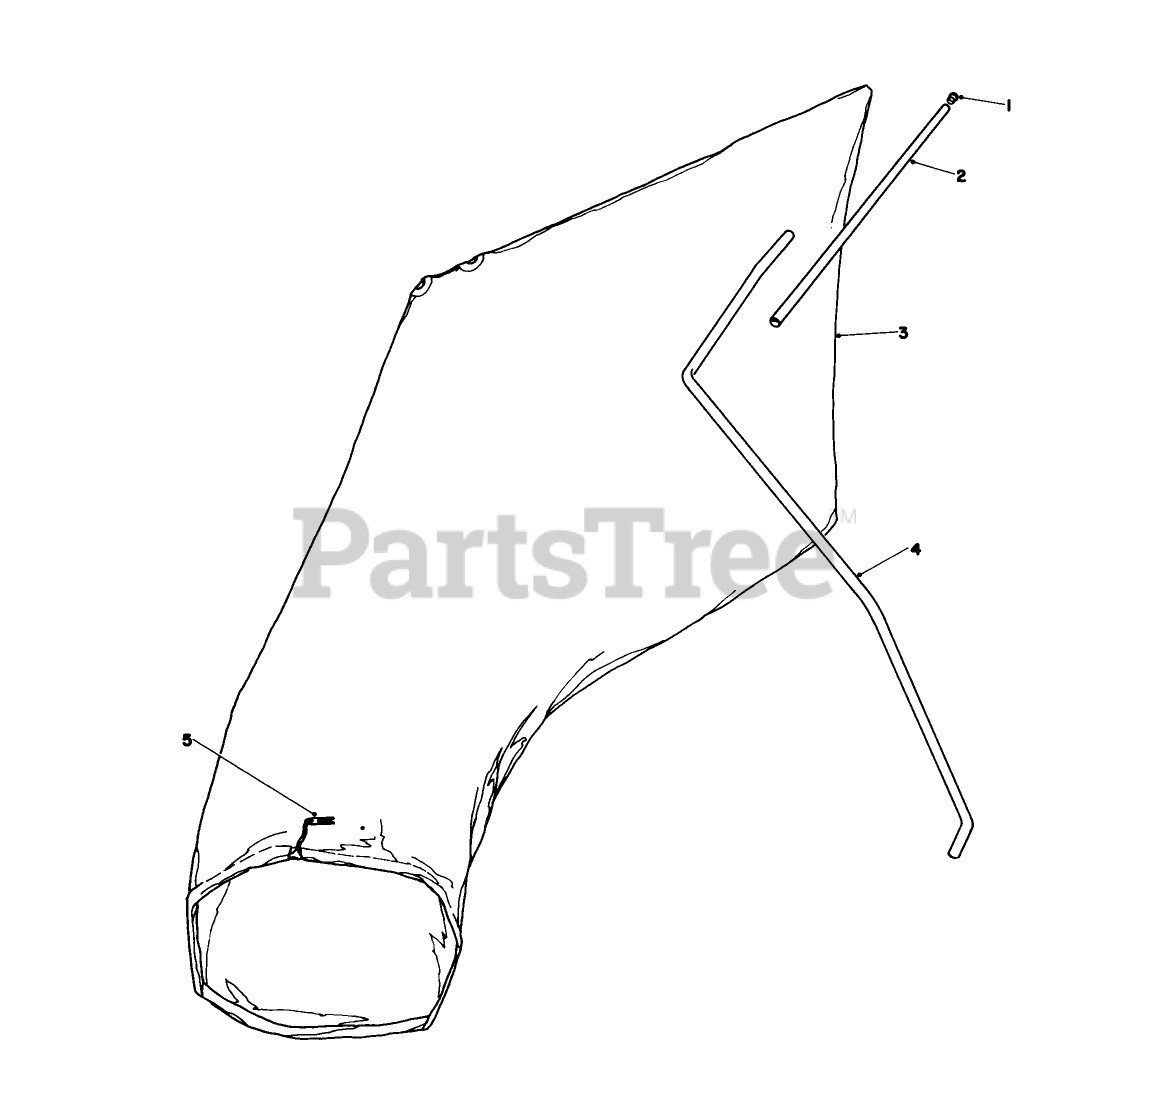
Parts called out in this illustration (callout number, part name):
2	BAG HANGER TUBE
3	Bag (Incl. Ref. #5)
4	HANGER ROD
5	BAG CORD FASTENER
